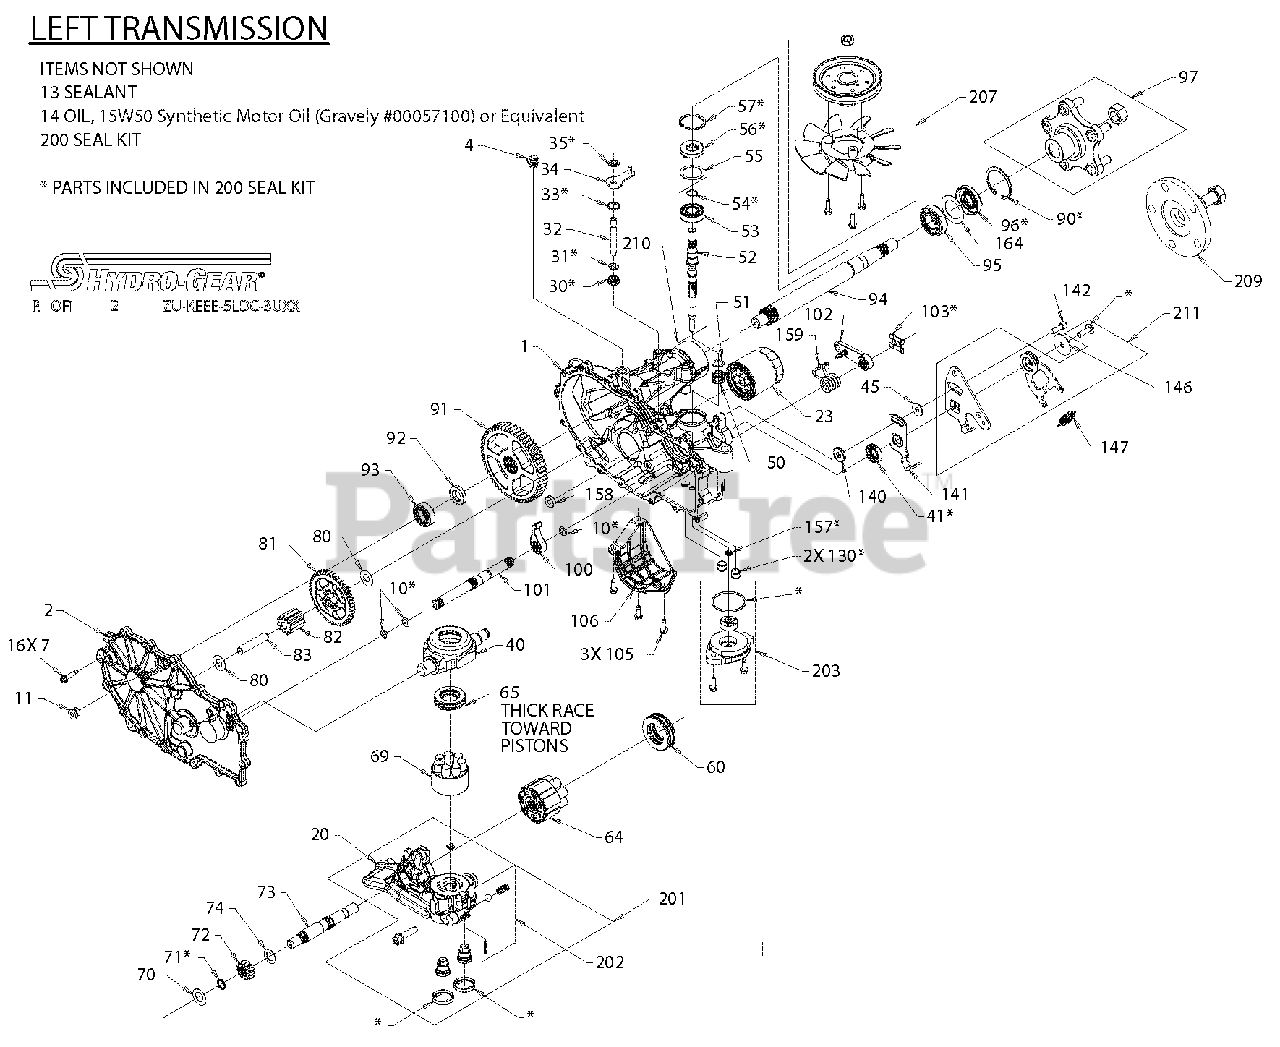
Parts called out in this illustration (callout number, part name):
7	HFHCS 1/4-20 X 1.25
13	SEALANT
23	FILTER, OIL
30	SEAL, LIP .375 X .75 X .25
31	RING, RET .375 EXTERNAL
33	RING, RET .750 INTERNAL
34	ARM, BYPASS
35	RING, RTNG .375 EXT
40	TRUNNION, SWASHPLATE
41	SEAL, LIP 18 X 32 X 7
45	WASHER .34 X .88 X .06 SPRING, BLOCK
50	SPRING, BLOCK
51	WASHER-FLAT .59 x .79 x .04
55	WASHER 1.23 X 1.56 X .04
56	SEAL, LIP 17 X 40 X 7
57	RING, RET 2.06 INT
60	BEARING, THRUST
64	ASS'Y, CYLINDER BLOCK, 16cc
65	BRG, THRUST BALL 30 X 52 X 13
69	ASS'Y, BLOCK, 7 PISTON
70	WASHER .63 X 1.00 X .05
71	RING, RET .62 EXT
74	WASHER .72 X 1.16 X .04
80	WASHER .5 X 1.0 X .03
83	JACK SHAFT (PIN)
90	RING, RET 2.06 INT
95	BRG, BALL 1.0 x .52 x .15 OPEN 6205M
96	SEAL, LIP TC4 1.0 x 2.06 x .38
97	KIT, HUB, 5 BOLT
102	KIT, HANDLE ACTUATING
103	CLIP, RETAINING
105	SCREW, HEX FLANGE
140	SPACER .320 x 1.005 x .179
141	ARM, NEUTRAL LEFT
142	SHCS 5/16-24 x 1.00 (PATCH)
146	WASHER, .343 x 1.500 x .062
147	SPRING, EXTENSION RTN-34LBS
157	SEAL, LIP .281 x .420 x .16
158	MAGNET, RING
200	KIT, SEAL
201	KIT, CENTER SECTION, LH, CHRG
203	KIT, CHARGE PUMP
210	KIT, INPUT SHAFT
